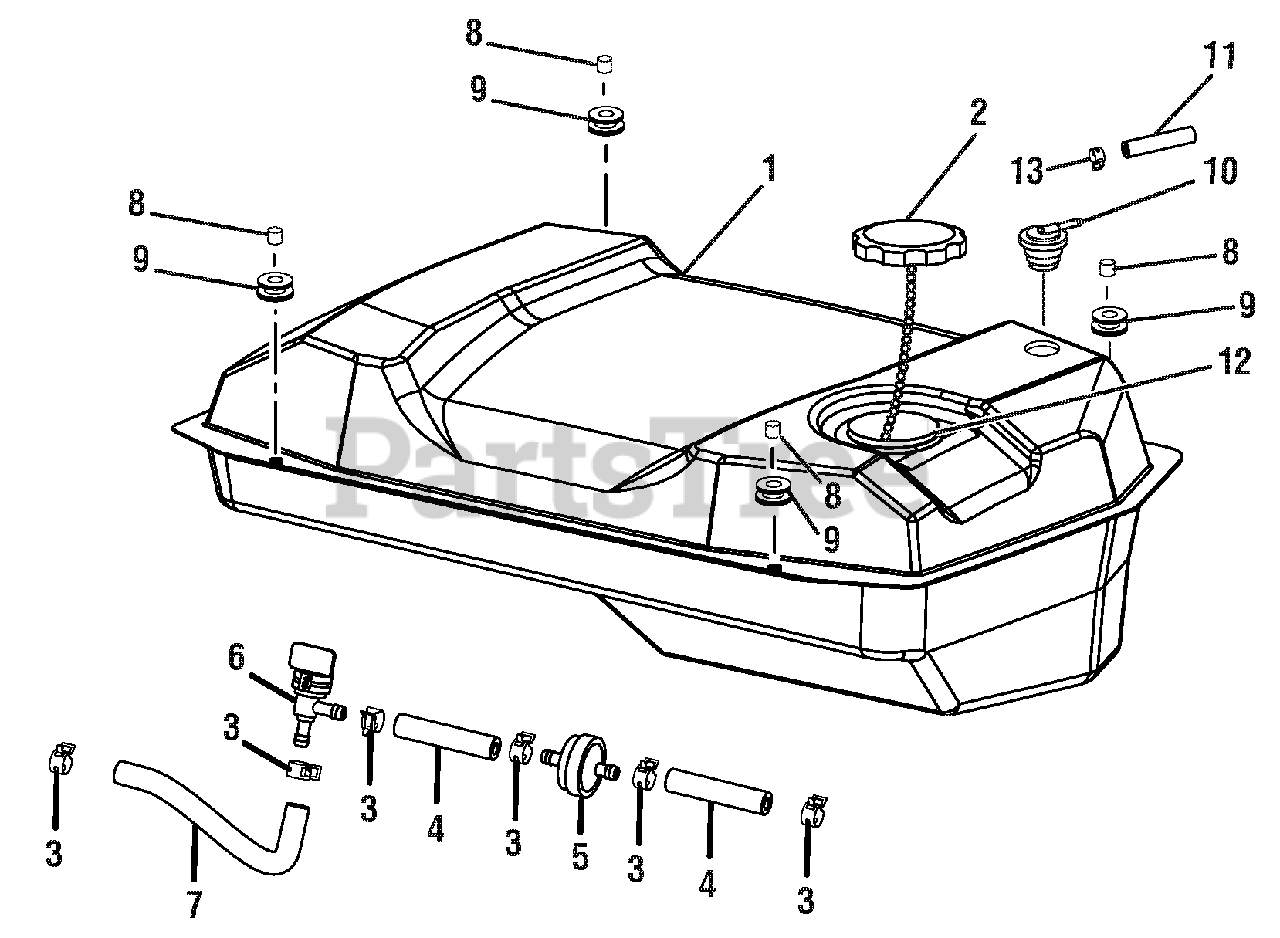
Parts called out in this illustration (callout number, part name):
1	FUEL TANK
2	FUEL TANK CAP
3	FUEL LINE CLAMP (1/2 IN.)
4	FUEL LINE (105 MM)
5	FUEL LINE FILTER
6	FUEL SHUT OFF VALVE
7	FUEL LINE (208MM)
8	SPACER (FUEL TANK ISOLATOR)
9	ISOLATOR (FUEL TANK)
10	VAPOR VENT
11	ROLLOVER HOSE
12	RING CLIP
13	FUEL LINE CLAMP
